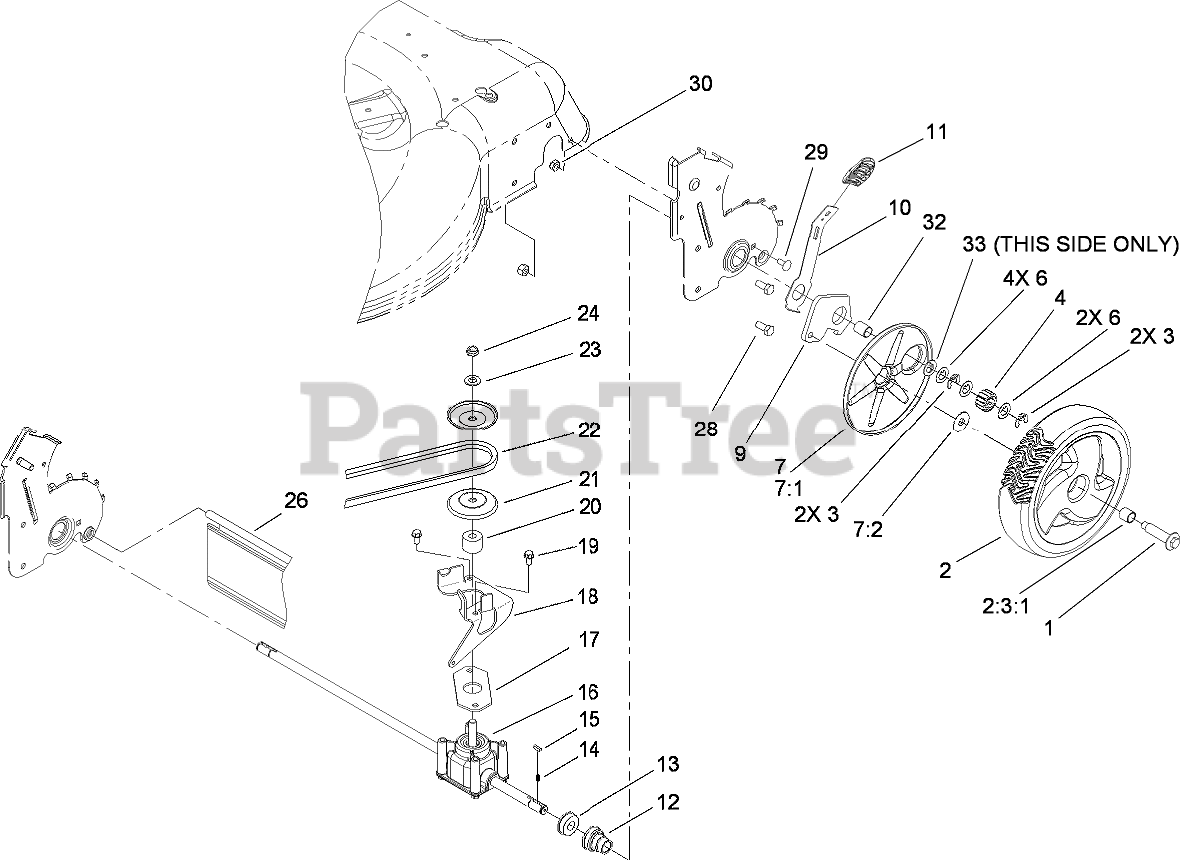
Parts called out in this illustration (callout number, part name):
1	BOLT-SHOULDER
2	Wheel Gear ASM
2:3	Wheel ASM
2:3:1	BUSHING
3	RING-CLIP, LOCKING
4	Gear-Pinion, 15t
6	Washer-Thrust
7	WHEEL COVER ASM
7:1	COVER-WHEEL
7:2	WASHER-STEPPED
9	ARM-PIVOT, REAR
10	ARM-SPRING
11	Knob-Lever, HOC
12	RETAINER-BUSHING, HOC
13	BEARING-BALL
14	SPRING-COMPRESSION
16	TRANSMISSION ASM
17	GASKET-GEARBOX
18	BRACKET-PIVOT
19	SCREW-HWH
20	SPACER
21	PULLEY-HALF
22	BELT-V
23	WASHER-FLAT
24	NUT-HEX
26	SHIELD-TRAILING
28	SCREW-HH
29	SCREW-CARR
30	NUT-LOCK, NI
32	BUSHING-SLEEVE
33	WASHER-THRUST
